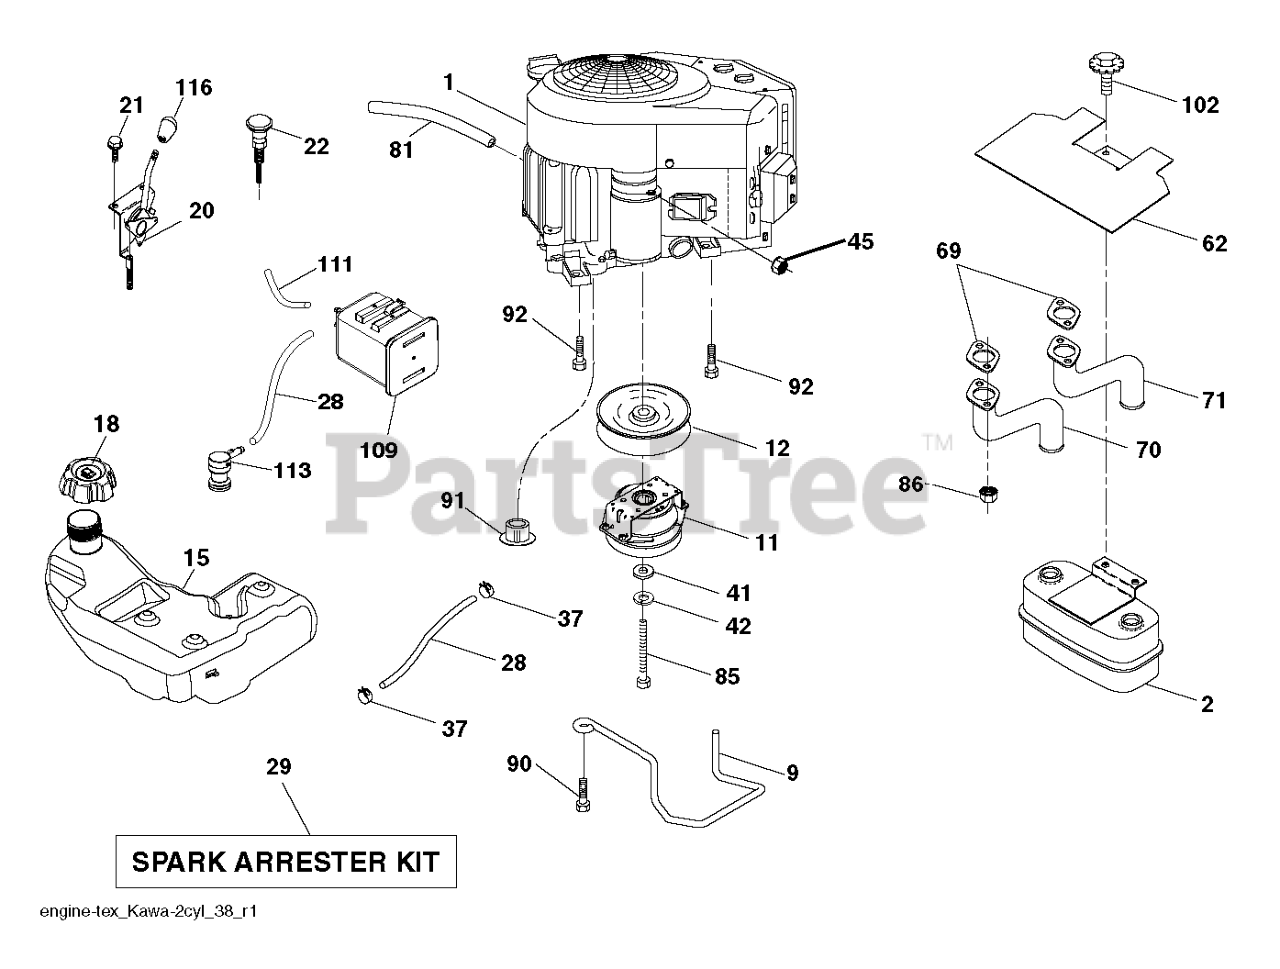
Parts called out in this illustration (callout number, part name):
2	MUFFLER.ASM.TWN.EXTNDED.DFLCTR
9	KEEPER BELT ENGINE
11	RB.CLUTCH.OGURA.4.4.PD
12	PULLEY.ENGINE.TUFFTORQ
15	TANK.ASM.FUEL.3GA.CARB
18	CAP.ASM.FL.RITCH.3"E10.SYM.498
20	CONTROL.THROTTLE.PRO.
21	SCREW.#10 X 0.750.BOS
22	CONTROL, CHOKE
28	LINE.FUEL.64"REAR.EMIS
29	KIT.SPARK ARRESTOR 794945 B&S
37	HOSE CLAMP
42	LOCKWASHER
45	NUT
62	SHIELD.HEAT.MUFFLER
70	TUBE.EXHAUST.LH.FR961/FR730
71	TUBE.EXHAUST.RH.FR961/FR730
81	TUBE, DRAIN OIL ASM.
85	BOLT HEX 7/16-20X4-1/4"
86	NUT.HEX.FLANGE.TOPLOCK
87	BOLT, 5/16-18 X 1 3/4
90	SCREW 3/8-16X1
91	BUSHING.1.375OD
92	SCREW 3/8-16X1
109	CANNISTER, CARBON
111	RP PURGE LINE
113	VALVE.SLANT.CARTRDG.90 DEG.TEX
116	KNOB - SHIFT
